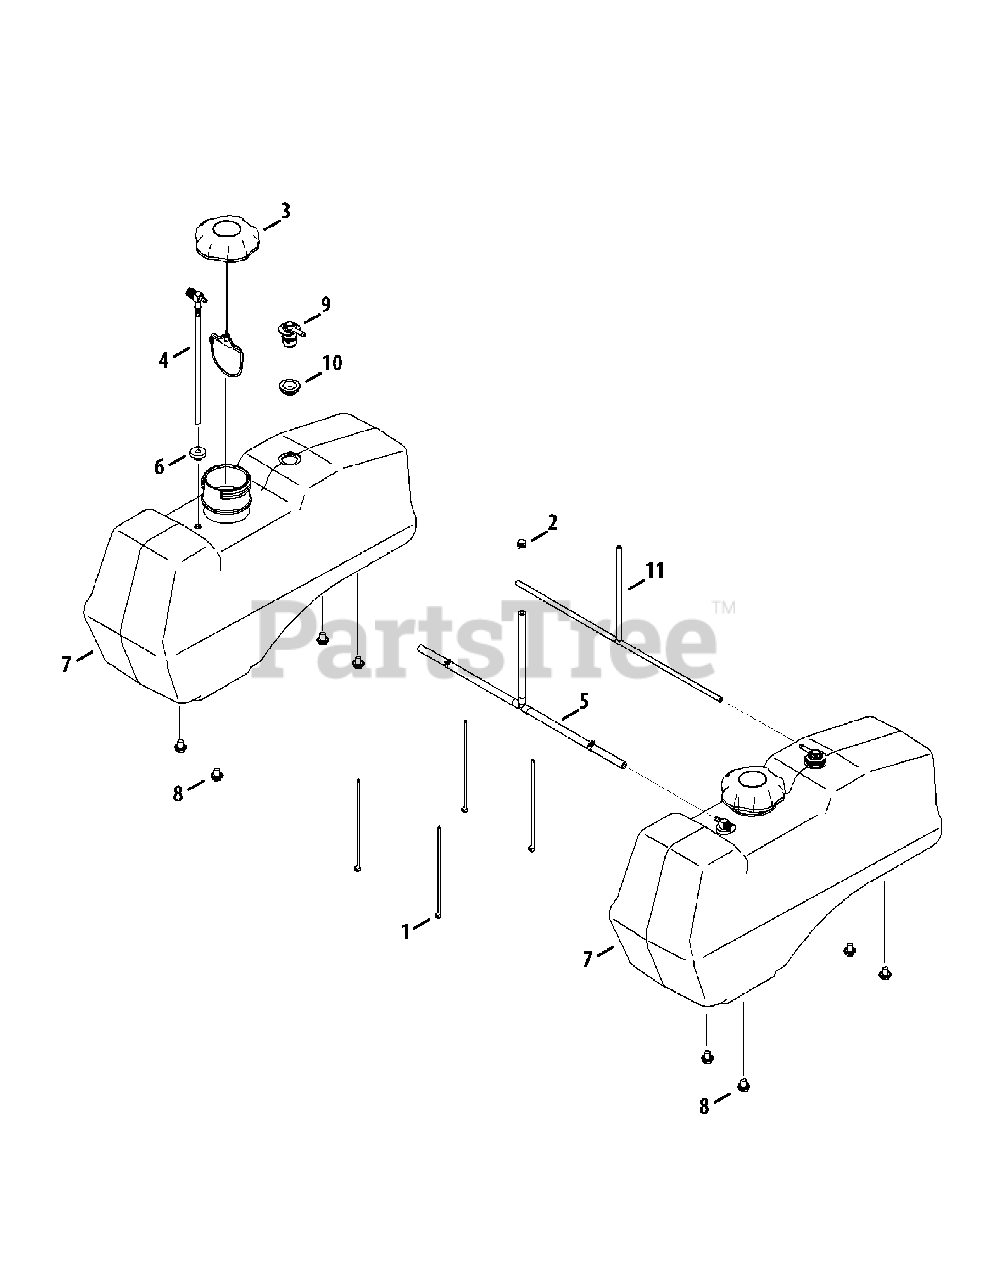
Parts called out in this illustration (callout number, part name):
1	Cable Tie
2	Hose Clamp, SAE #4: 1/4-5/8, SS
3	Fuel Cap, 3.5
4	Fuel Fitting
5	Fuel Hose Assembly
5	Hose, 1/4" Fuel Line
5	Clamp, Union
5	Tee Fitting, Fuel
6	Grommet, Fuel Tank
7	Fuel Tank Assembly
8	Hex Cap Screw, 3/8-16 x .50 Flange
9	Fuel Rollover Valve
10	Rubber Grommet
11	Fuel Hose Assembly
11	Hose, 3/16" Fuel Line
11	Tee Fitting, Fuel
